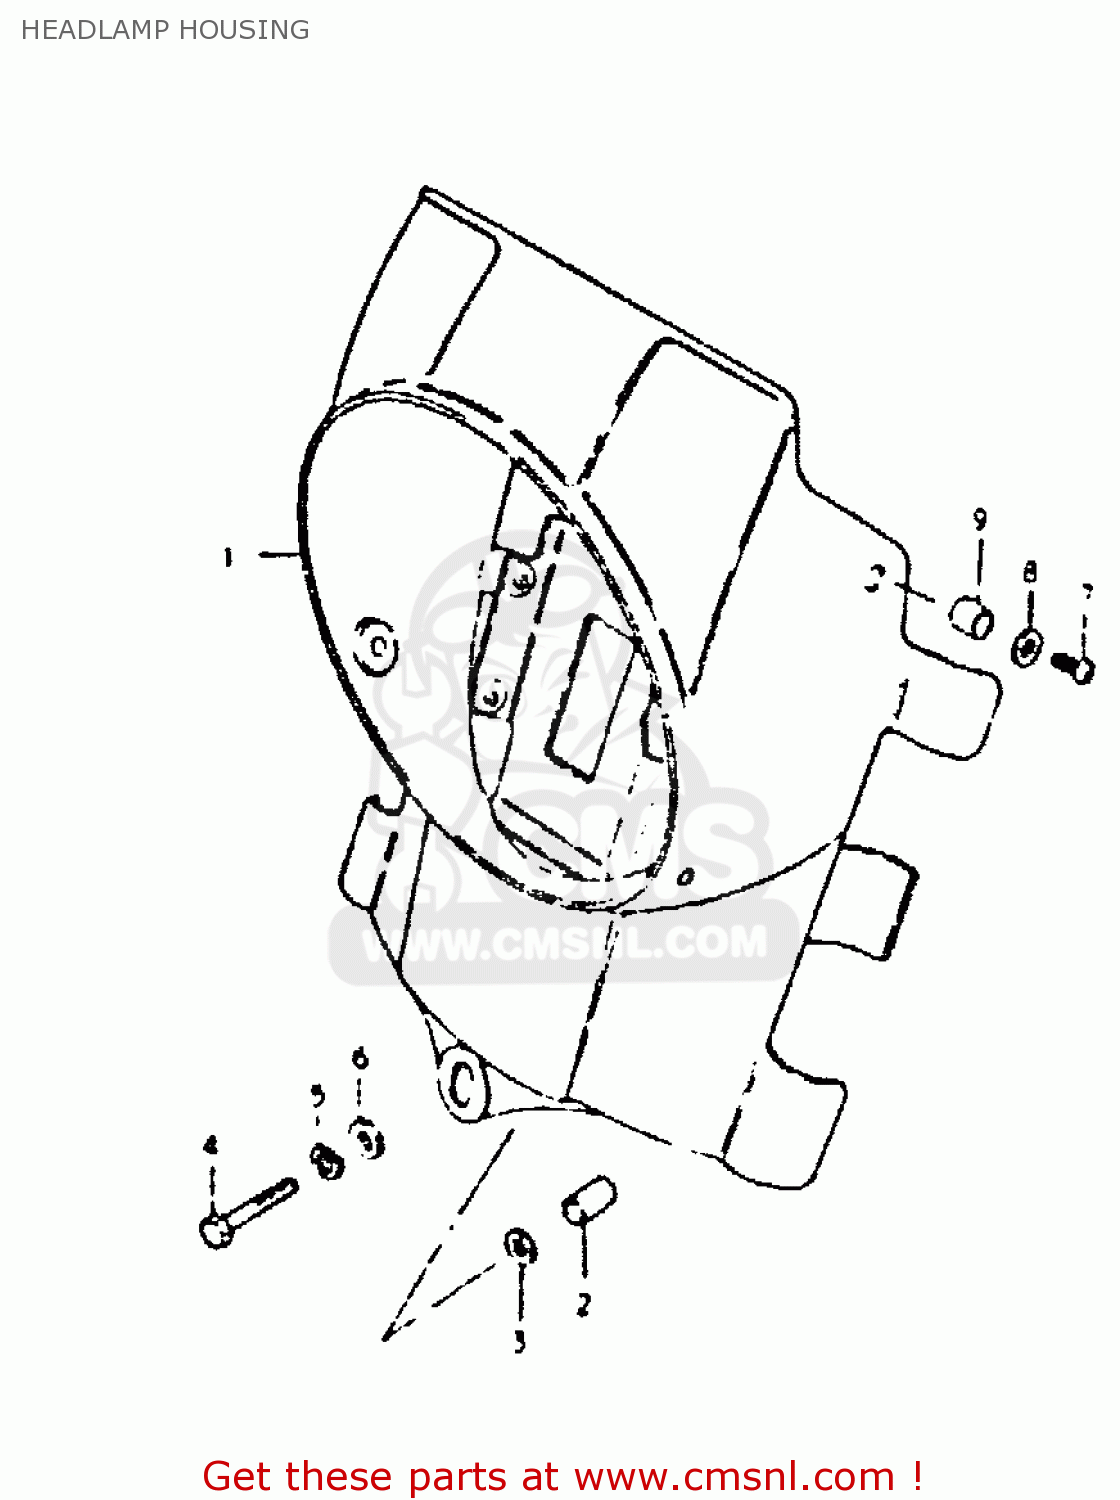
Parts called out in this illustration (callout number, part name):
1	HOUSING,HEADLAMP
2	SPACER (6.5X10.5X13.5)
3	WASHER
4	BOLT
5	LOCK WASHER
6	WASHER (6.5X20X1.2)
7	SCREW
8	WASHER (5.5X18X1.6)
9	SPACER (5.5X8X4)
